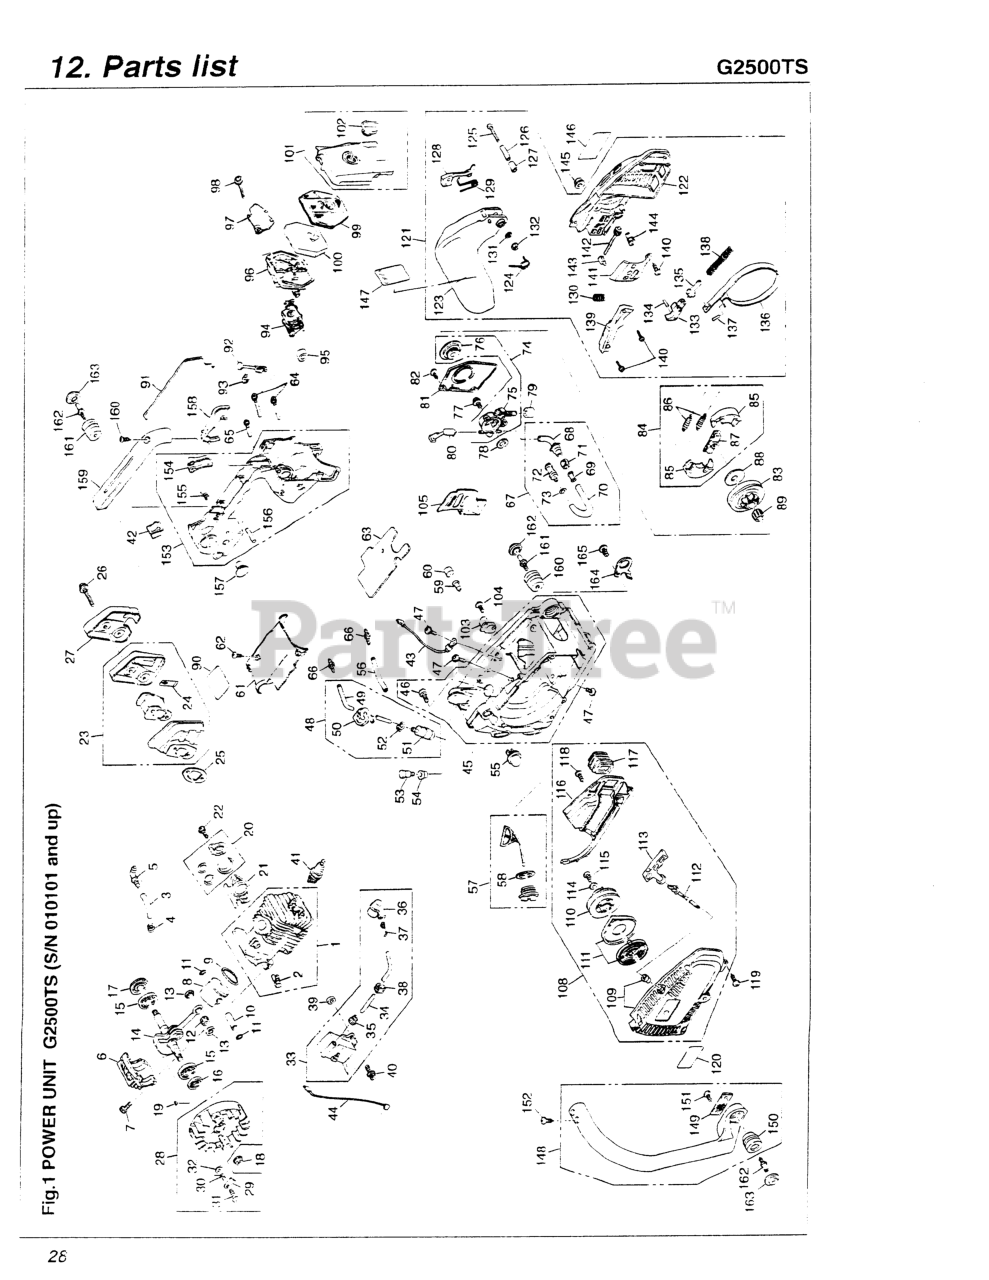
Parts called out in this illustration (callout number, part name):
1	CYLINDER COMPLETE
6	CRANKCASE
7	BOLT, M5 X 20
9	RING, PISTON
10	PIN, PISTON
11	RING, SNAP (RPLS 1101-41320)
13	WASHER
14	SHAFT COMPLETE
16	SEAL, OIL
17	SEAL, OIL
19	KEY
20	PIPE SET, USE 2841-06011
22	SCREW (REPLACES -30414)
23	MUFFLER ASSEMBLY
24	ARRESTER, SPARK
25	GASKET (USE 2841-15210)
26	SCREW
27	COVER, MUFFLER
28	ROTOR ASSEMBLY
29	PAWL
30	SPRING, RETURN
31	SCREW
32	WASHER
33	MODULE ASSEMBLY
35	CAP
36	CAP, PLUG
37	SPRING PLUG (RPLS 3310-71320)
40	BOLT, M4 x 20
42	SWITCH ASSEMBLY
43	CORD, EARTH
44	CORD, SWITCH
47	SCREW
49	PIPE, FUEL
51	5500-85400 (RRLS. 1750-85300)
52	CLIP (REPLACES 2841-31280)
53	BREATHER ASSEMBLY
54	GROMMET
55	PUMP ASSEMBLY
56	PIPE
58	GASKET
59	VALVE (RPLS -23120)
60	SEAL, BREATHER
61	COVER, TOP
62	SCREW
65	PIPE
66	JOINT (USE 3350-34320)
67	PIPE,OIL COMPLETE
68	PIPE, OIL
72	FILTER, OIL (RPLS -23130)
73	RING, SNAP (RPLS 1101-41320)
75	PUMP, OIL
76	WORM GEAR
77	SCREW (REPLACES -30414)
78	WASHER
79	SEAL
80	PIPE, OUTLET
81	COVER, PUMP
82	SCREW
83	DRUM, CLUTCH
85	SHOE, CLUTCH
87	BOSS, CLUTCH
89	BEARING
90	LABEL (G2500TS)
91	ROD, THROTTLE
92	ROD, CHOKE
93	GROMMET
94	CARBURETOR
96	PLATE, BASE
97	PLATE
99	CLEANER, AIR
100	ELEMENT
101	COVER, CLEANER COMPLETE
102	KNOB (RPLS 3356-83322)
103	CATCHER, CHAIN (RPLS. -53411)
105	PLATE, GUIDE-A
108	STARTER, RECOIL
109	CASE, RECOIL COMPLETE
111	SPRING COMPLETE
113	KNOB (RPLS -75420)
114	WASHER, FLAT (USE 182303)
116	COVER, FAN
117	PIPE, AIR
118	SCREW
119	SCREW
120	LABEL (G2500TS)
121	BRAKE ASSEMBLY
122	COVER, CHAIN
125	SCREW
127	SPACER (RPLS -54210)
131	WASHER, M5 X .8
132	NUT (B)
133	LEVER, BRAKE COMPLETE
135	ARM, SLIDE
137	PIN
138	SPRING, BRAKE (RPLS. 50030121)
140	SCREW (REPLACES 50030272)
142	SCREW
143	NUT
144	GEAR
145	NUT
146	LABEL (G2500TS)
147	LABEL, WARNING (G2500TS)
150	DAMPER
153	HANDLE, RIGHT COMP
155	SPRING
159	COVER, GRIP
160	SCREW
161	DAMPER
162	BOLT, STOPPER
163	CAP, DAMPER
164	HANGER
165	SCREW (REPLACES 50030272)
